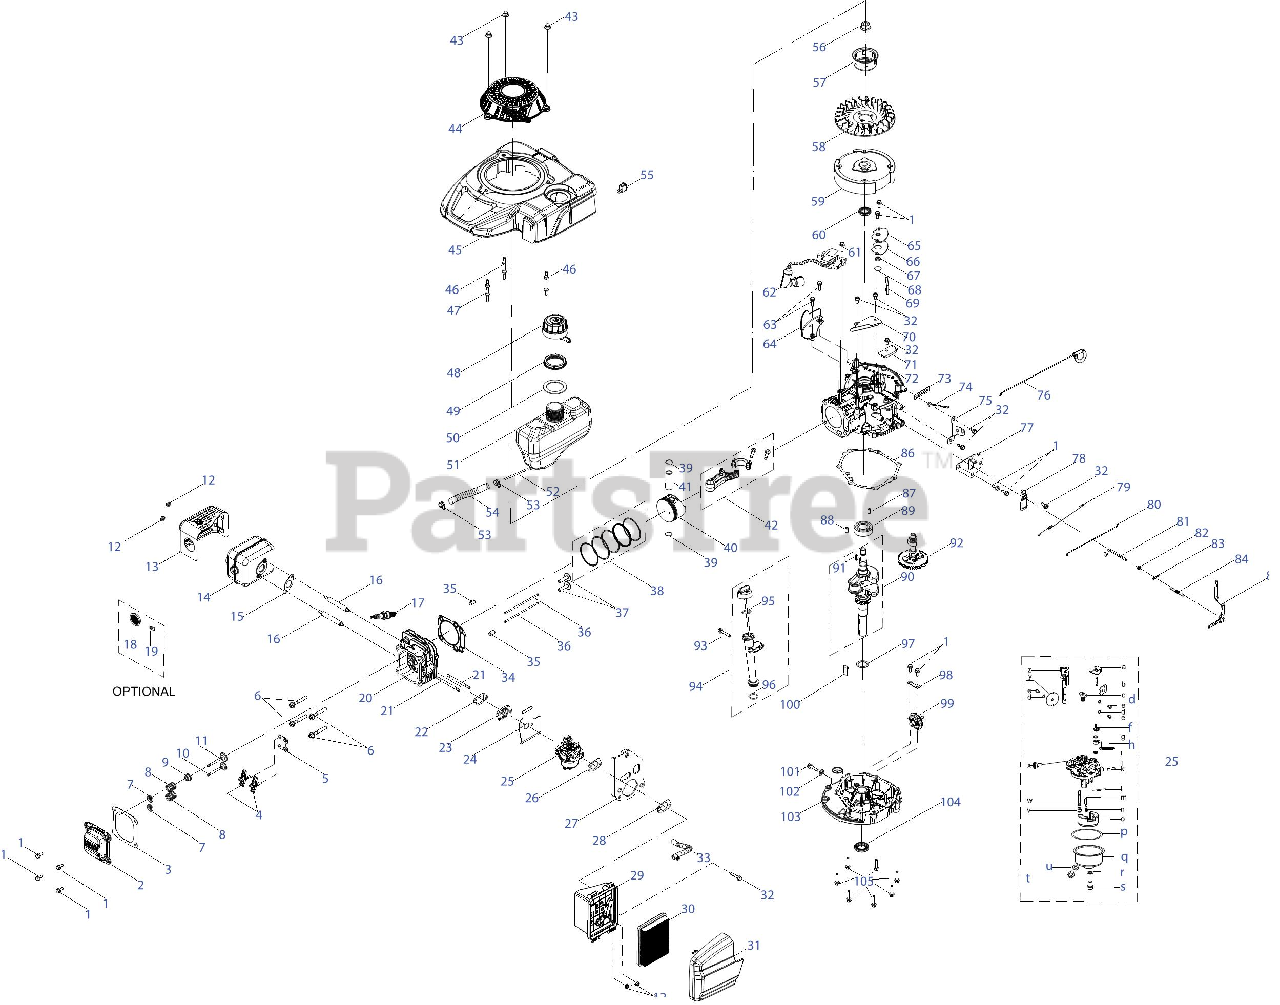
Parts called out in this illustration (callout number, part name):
1	Bolt M6x14
2	Valve Cover
3	Valve Cover Gasket
4	Rocker Arm Assembly
5	Push Rod Guide
6	Bolt M8x54
7	Valve Spring Retainer
8	Valve Spring
9	Intake Valve Seal
10	Exhaust Valve
11	Intake Valve
13	Muffler Shield
14	Muffler Assembly
15	Muffler Gasket
16	Muffler Stud M6x95
17	Spark Plug/F5RTC
18	Spark Arrestor
19	Spark Arrestor Screw
20	Cylinder Head
21	Carb Stud M6x87
22	Carburetor Insulator Gasket
23	Carburetor Insulator
24	Carburetor Gasket
25	Carburetor Assembly
26	Air Filter Base Gasket
27	Air Filter Bracket
28	Choke Temp Control Bracket Gasket
29	Air Filter Base
30	Air Filter Element, Paper
31	Air Filter Cover
32	Bolt M6x12
33	Breather Hose Assembly
34	Cylinder Head Gasket
35	Cylinder Head Dowel Pin ?10x16
36	Push Rod
37	Tappet
38	Piston Ring Set
39	Piston Pin Snap Ring
40	Piston
41	Piston Pin
42	Connecting Rod Assembly
43	Starter Acorn Nut
44	Starter Recoil Assembly
45	Engine Shroud Assembly
46	Shroud Stud M6x78.5
47	Shroud Stud M6x74
48	Fuel Cap Assembly
49	Fuel Tank Upper Grommet
50	Fuel Tank Nut
51	Fuel Tank
52	Fuel Filter
53	Fuel Hose Clamp
55	Ignition Switch
56	Flywheel Nut M14
57	Starter Cup
58	Cooling Fan
60	Upper Crankshaft Seal
61	Bolt M6x20
62	Ignition Coil Assembly
63	Bolt M6x25
64	Engine Brake Cover Plate
65	Breather Cover Plate
66	Breather Gasket
67	Breather Valve Spring
68	Breather Valve
69	Breather Screen
70	Air Vane Cover Plate
71	Ground Wire Cover Plate
73	Flexible Clamp, Ignition Coil
74	Grounding Wire
75	Choke Control Bracket
76	Choke Control
77	Component Bracket
78	Governor Shield
79	Throttle Linkage Spring
80	Throttle Linkage
81	Governor Arm Shaft
82	Governor Seal
83	Governor Arm Shaft Cotter Pin
84	Governor Spring
85	Governor Arm Assembly
86	Crankcase Cover Gasket
87	Crankcase Cover Dowel Pin ?7x14
88	Crankcase Cover Dowel Pin ?9x14
89	Main Bearing
90	Crankshaft Assembly
91	Flywheel Key
92	Camshaft Assembly
93	Bolt M6x35
94	Dipstick Assembly
95	Dipstick / Oil Fill Tube O-Ring
96	Dipstick / Oil Fill Tube O-Ring
97	Crankshaft Thrust Washer
98	Governor Gear Mounting Plate
99	Governor Gear/Shaft Assembly
100	Oil Return Seal
101	Oil Drain Plug
102	Oil Drain Plug Washer
103	Crankcase Cover
104	Lower Crankshaft Seal
105	Bolt M6x28
